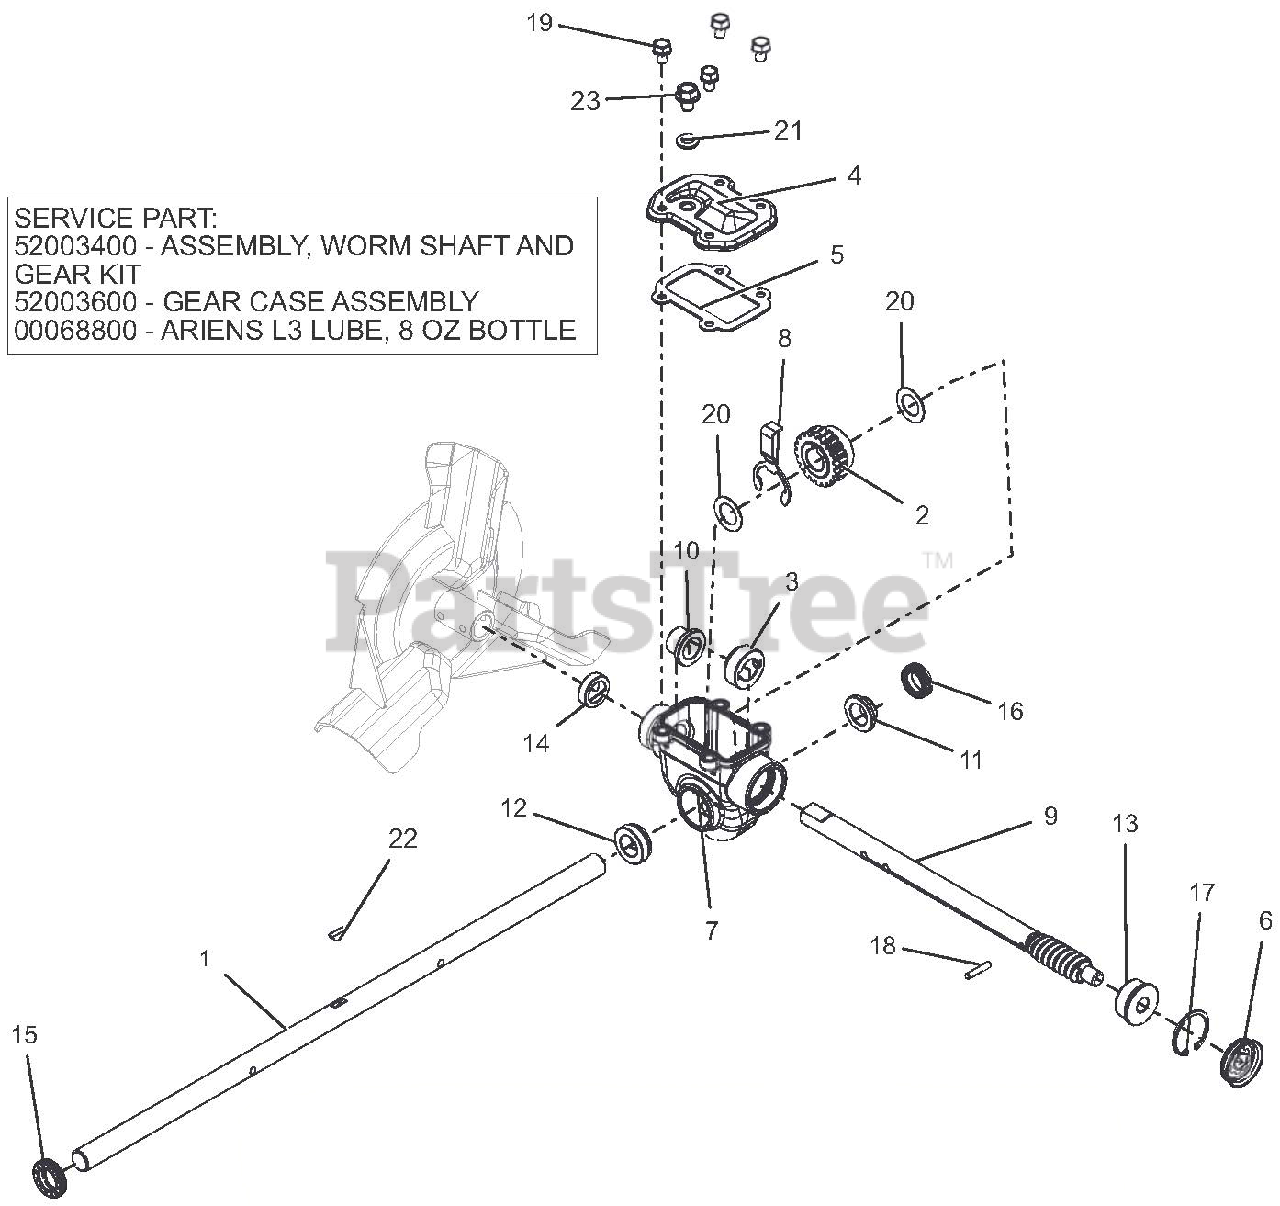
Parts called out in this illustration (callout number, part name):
1	SHAFT, RAKE - 24" (.750 DIA)
2	WORM GEAR
3	THRUST COLLAR, .75" ID SLIPFIT
4	COVER, TOP - COMPACT
5	GASKET, TOP - COMPACT GEARCASE
6	COVER, GEAR CASE 1.50"
7	GEARCASE, COMPACT ALUMINUM
8	BUSHING RETAINER, COMPACT
9	SHAFT, WORM - COMPACT
10	BSHG-FLG .755X.878X.75X1.25
11	BSHG-FLG .755X.878X.424X1.25
12	BSHG-FLG COMPACT, RIGHT
13	BSHG-FLG .503X1.303X.62X1.465
14	SEAL-OIL .748X1.125X.312 TB2-H
15	SEAL-OIL .748X1.300X.250 TBC29
16	SEAL-OIL .748X1.125X.312 TBC29
17	RG-RTNG-INT 1.500X.050
18	PIN-STR .188X1.00 6150
19	BOLT, SEMS .31-18X.50 GR5 YWZC
20	WSHR-FL-STL .760X1.225X.032 YZ
21	WSHR-BND-SEAL .38X.75X.11 GALV
22	KEY-WDRF .19X.63 HRD #61
23	@SCR-ROLOK .38-16X.50 HWH YWZC
24	GEAR CASE, 24" ALUM SM TOP-LD
25	ARIENS L3 LUBE, 8 OZ BOTTLE
